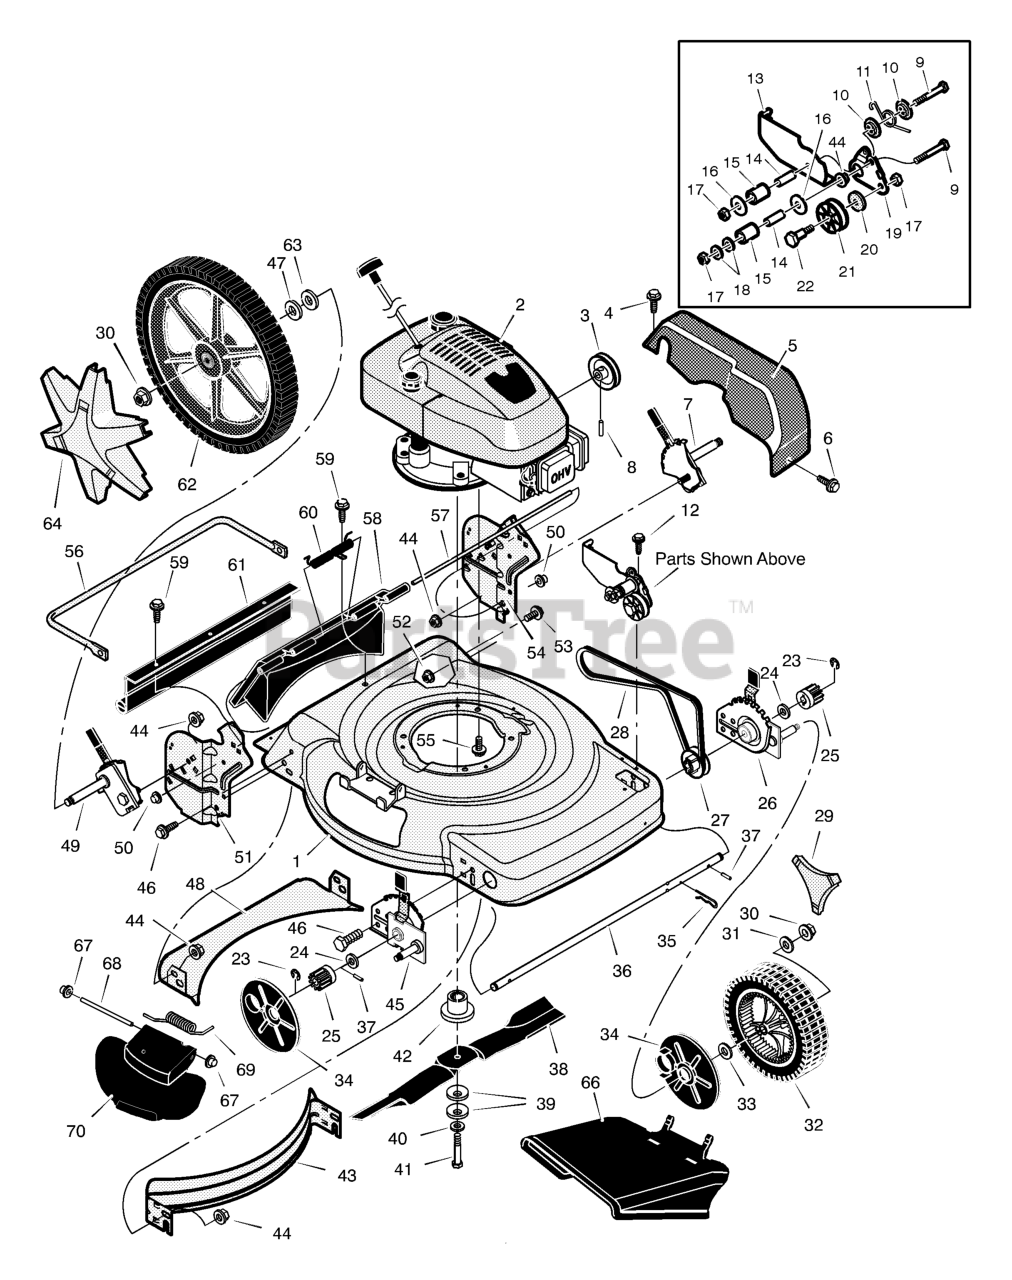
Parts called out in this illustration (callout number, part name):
1	Housing
2	Engine
3	Pulley, Drive
5	Cover, Belt (Gray)
7	Adjuster, Left Rear Height
8	Pin, Spring
10	Spacer, Idler Arm
12	Screw
13	Bracket, Idler Support
14	Bearing, Idler
15	Pulley, Idler
17	Nut
18	Washer
19	Arm, Pivot
20	Spacer, Idler
21	Pulley, Idler
22	Bolt, Shoulder
25	Gear, Pinion
26	Adjuster, Left Front Height
27	Pulley, Axle
29	Cap, Hub
30	Nut, Flange
31	Washer
32	Wheel & Tire, Front
34	Cover, Dust
35	Pin, Hair
37	Pin, Drive
39	Washer, Belleville
42	Adapter, Blade
43	Baffle, Front
44	Nut, Flange
45	Adjuster, Right Front Height
46	Bolt
48	Baffle, Rear
49	Adjuster, Right Rear Height
50	Push On Cap
51	Bracket, Right Handle
52	Nut, Flange
53	Bolt
54	Bracket, Left Handle
55	Bolt, Engine
57	Rod, Pivot
58	Door, Rear (Gray)
61	Guard, Rear
62	Wheel & Tire, Rear
64	Cap, Hub
66	Deflector, Chute
67	Push On Cap
68	Rod, Pivot
69	Spring, Torsion
70	Cover, Mulch (Gray)
